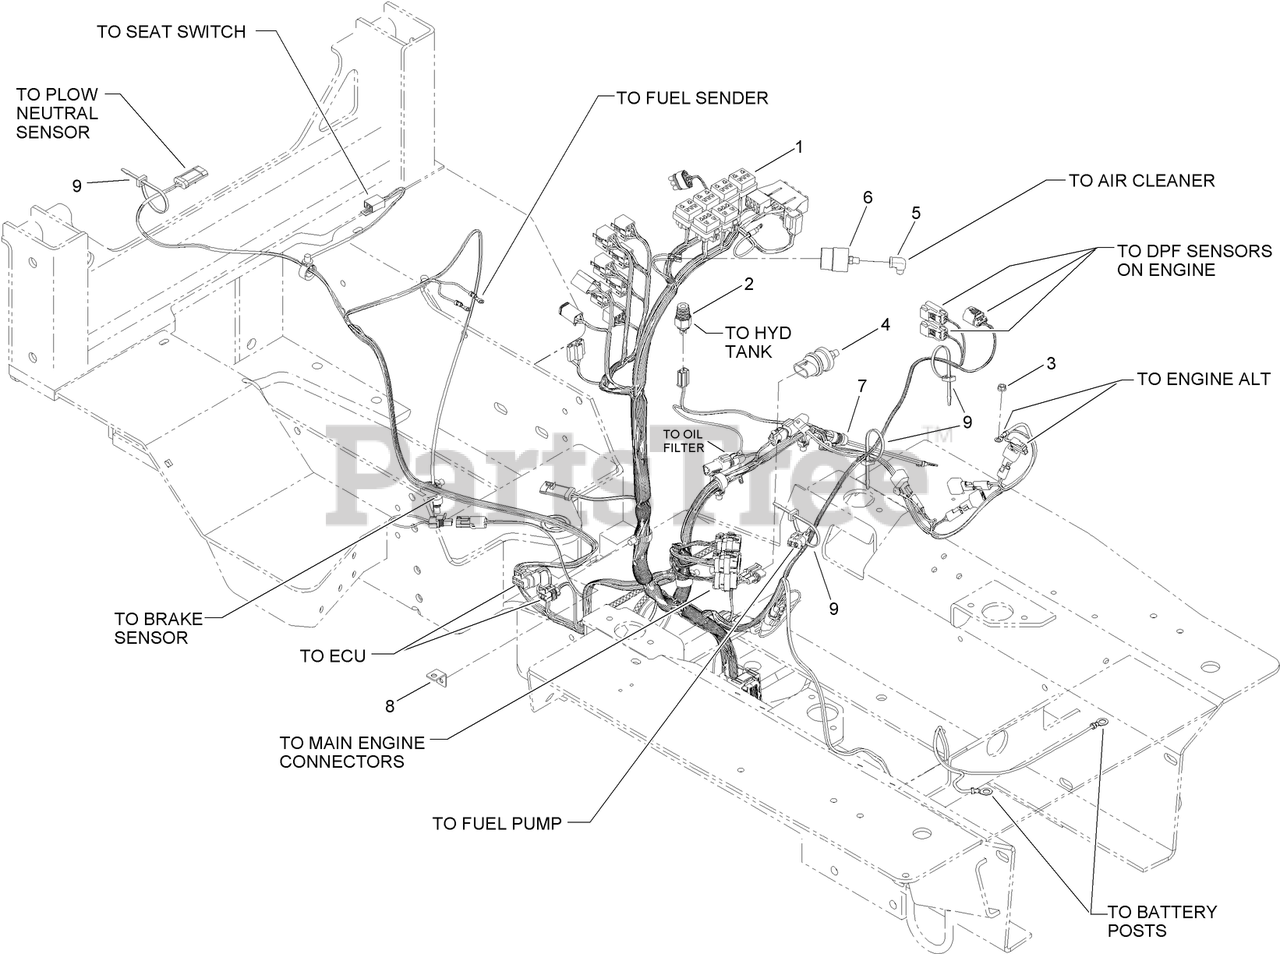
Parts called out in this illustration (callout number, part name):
1	HARNESS-WIRE
2	SWITCH-TEMP, 200 DEGREE
3	NUT-HF
4	SWITCH-PRESSURE, OIL
5	ELBOW
6	SWITCH-PRESSURE, VACUUM
7	HARNESS-WIRE, FUSIBLE LINK
8	BRACKET
9	TIE-CABLE
